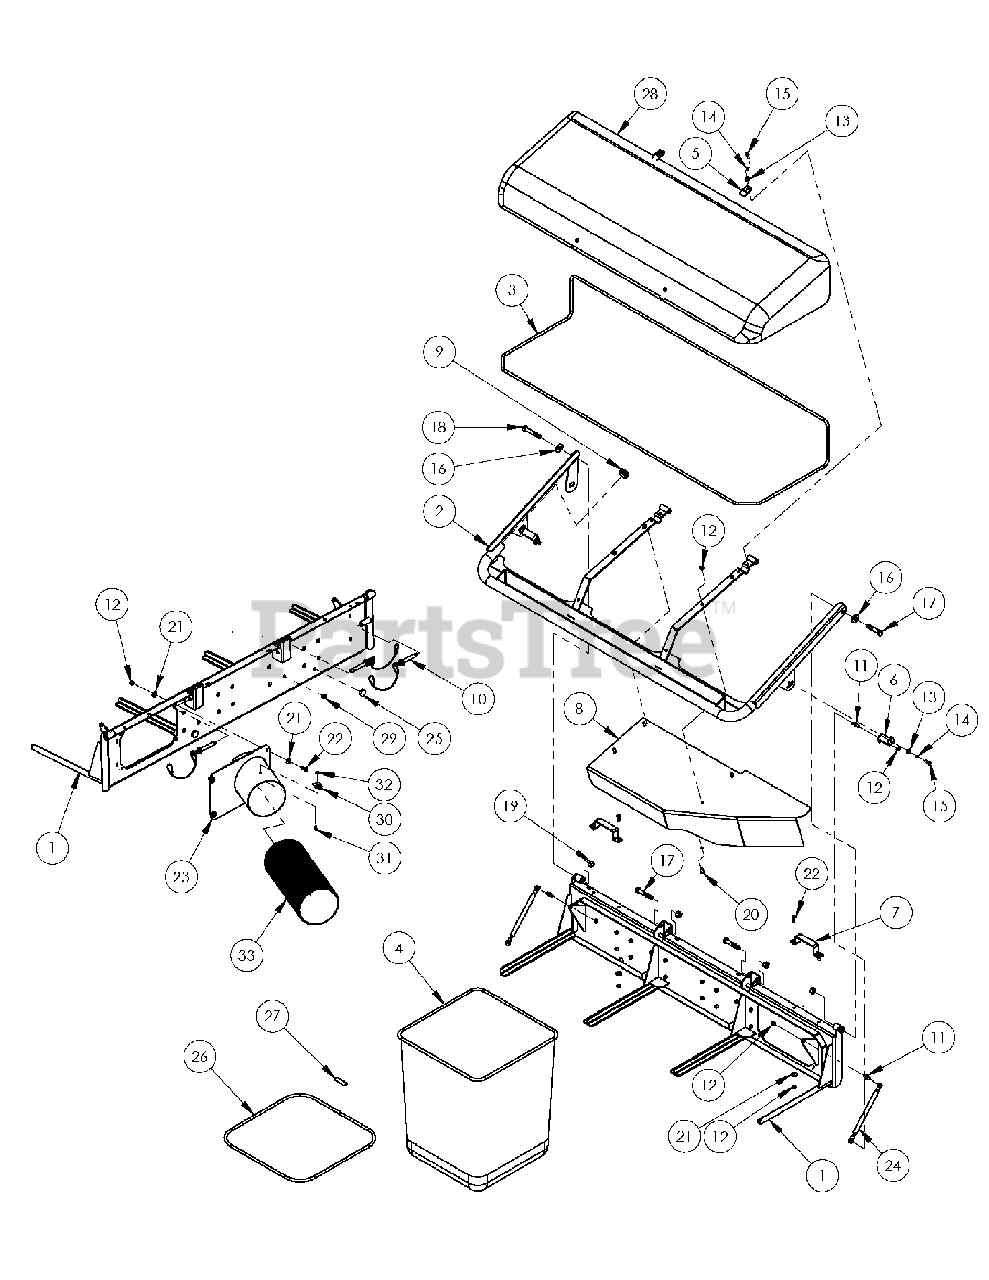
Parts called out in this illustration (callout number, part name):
1	3-BAG CATCHER BAG SUPPORT MOUNT
2	3-BAG CAP SUPPORT
3	AIR DOME FRAME, 3 BAG 3/8" ROD ONE
4	COMMERICAL CATCHER BAG
5	BRACKET SINGLE HOLE MOUNT
6	BRACKET GAS CYLINDER MOUNT
8	3 -BAG DEFLECTOR
9	PLUG, BLACK PLASTIC-1 1/2" TUBE
10	DETENT PIN W/ LANYARD 1/2" X 2 1/2" LONG
11	BALL JOINT
12	HEX NUT, NYLON INSERT 5/16"-18
13	FLAT WASHER 1/4"
14	LOCK WASHER 1/4"
15	CAP SCREW 1/4-20 X3/4" LONG
16	FLAT WASHER 1/2"
17	CAP SCREW 1/2"-13 X 2 1/2" LONG
18	CAP SCREW 1/2"-13 X 3" LONG
19	HEX NUT, NYLON INSERT 1/2"-13
20	PAN HEAD SCREW 5/16"-18 X 3/4" LONG
21	FLAT WASHER 5/16" LONG
22	CAP SCREW 5/16"-18 X 3/4" LONG
23	6" INLET TUBE ASSEMBLY
24	GAS CYLINDER
25	RUBBER BUMPER
26	COMMERCIAL GRASS BAG FRAME
27	PLASTIC FRAME CONNECTOR
28	AIR DOME CAP WITH "J" STRIP-PLAIN
29	PLUG, BLACK PLASTIC-7/16" HOLE
30	SPRING CLIP
31	MACHINE SCREW #10-24 X 1/2" LONG
32	HEX NUT, NYLON INSERT #10-24
33	3 BAG HOSE
